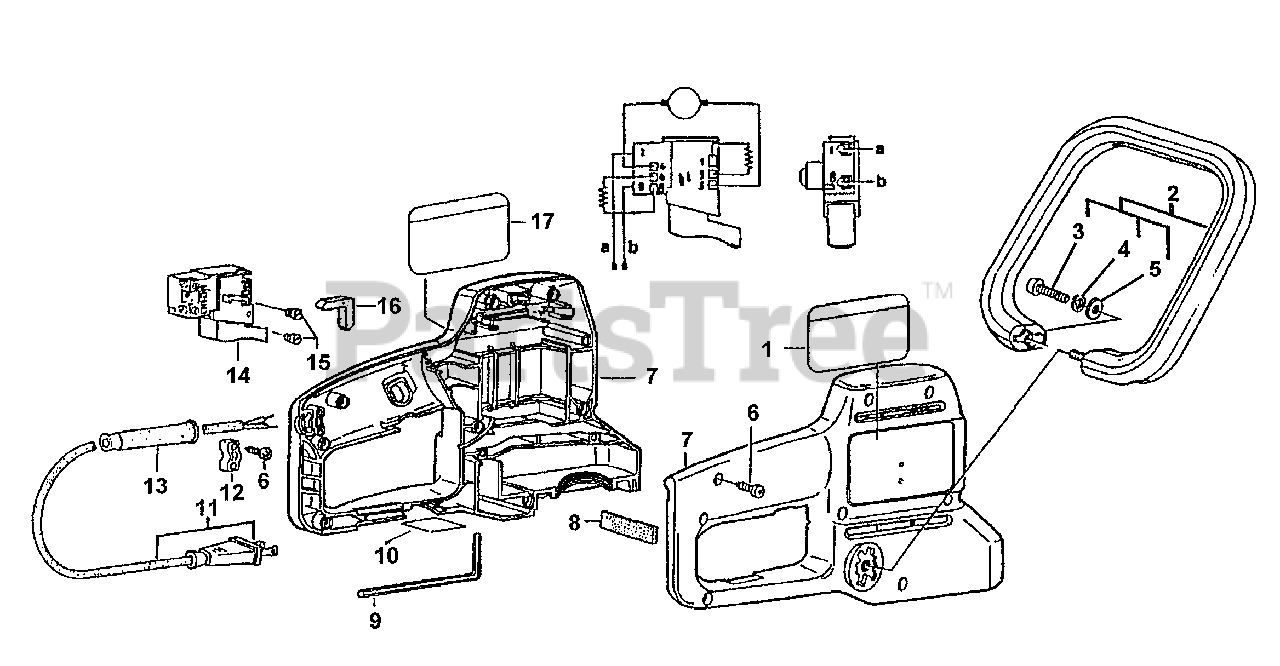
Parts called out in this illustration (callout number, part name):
1	LABEL, ECHO
2	HANDLE ASSY, AUXILIARY
3	SCREW
4	LOCKWASHER
7	HOUSING, MOTOR
8	PACKING, FELT
9	WRENCH, ALLEN
10	PLATE, NAME
11	CORD 115V 18/2
12	CLAMP, CORD
13	RELIEF, STRAIN
14	SWITCH, ON-OFF
15	SCREW
16	STRIP, SEAL
17	LABEL - ECHO
